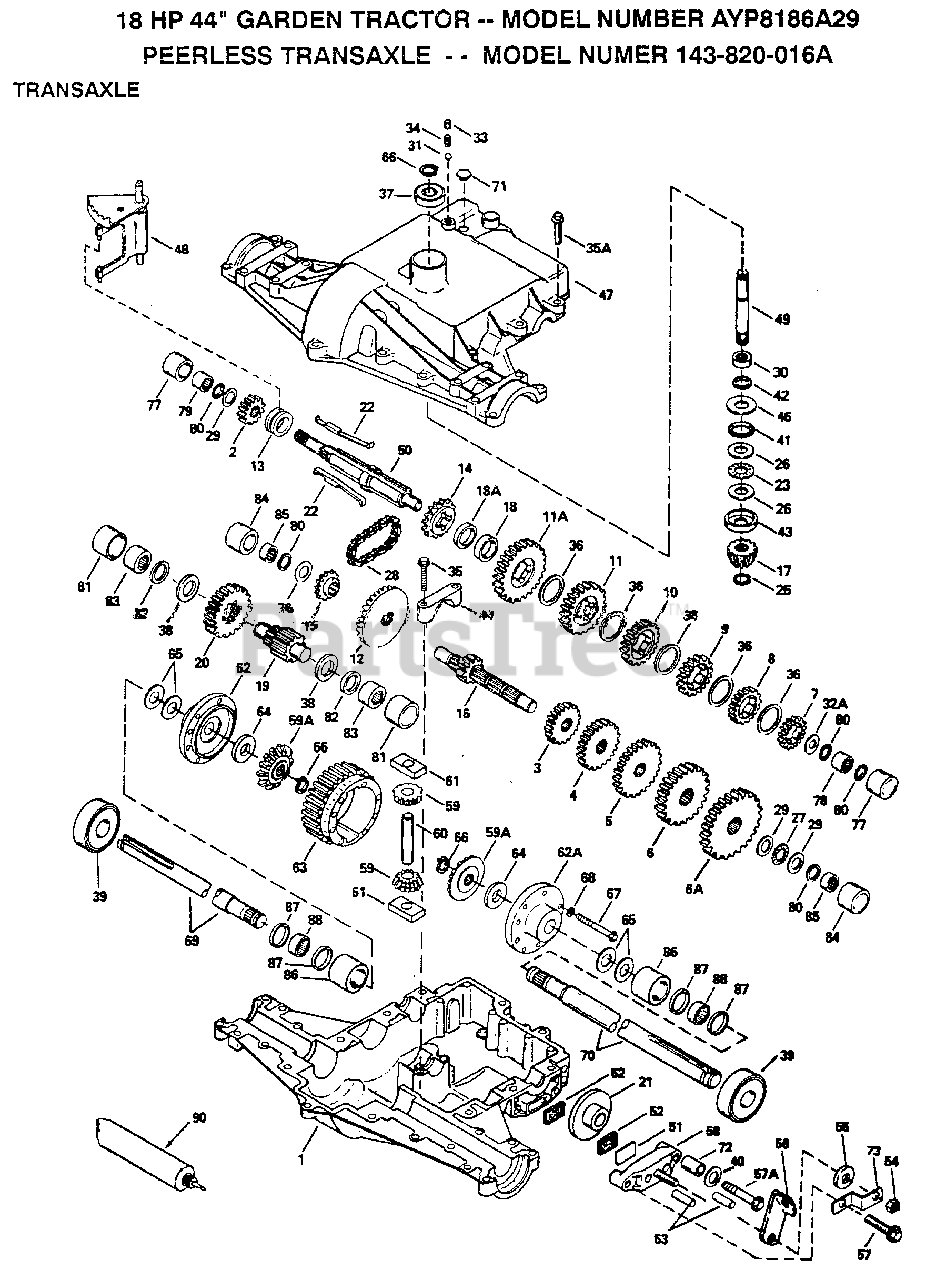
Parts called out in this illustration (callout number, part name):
1	CASE TRANSAXLE
2	GEAR, SPUR, 15T
3	GEAR, SPUR, 12 TEETH
4	GEAR, SPUR, 18 TEETH
5	GEAR, SPUR, 25T
6	GEAR, SPUR, 28T
6A	GEAR, SPUR, 31T
7	GEAR, SPUR, 19T
8	GEAR, SPUR, 22T
9	GEAR, SPUR, 25T
10	GEAR, SPUR, 32 TEETH
11	GEAR, SPUR, 37 TEETH
11A	GEAR, SPUR, 41T
12	GEAR BEVEL, 33T
13	COLLAR SHIFT
14	SPROCKET 18T (REV)
15	SPROCKET 9T
16	SHAFT COUNTER
17	BEVEL PINION, 13T
18	SPACER, .350/.340 THICK
18A	SPACER, .276/.268 THICK
19	SHAFT, OUTPUT, 9T
20	GEAR, OUTPUT, 35T
23	BEARING THRUST
25	RETAINING RING
26	WASHER THRUST
27	THRUST BEARING
28	CHAIN, ROLLER
29	WASHER THRUST
30	BEARING NEEDLE
31	BALL STEEL, 5/16" DIA.
33	SCREW, 3/8-16 X 3/8"
35	SCREW, 1/4-20 X 1-1/4
35A	SCREW HEX HD 5/16-18 X 1-1/4
36	WASHER THRUST
37	BEARING BALL
38	WASHER THRUST
39	BEARING BALL
40	WASHER FLAT
42	OIL SEAL 3/4
43	WASHER CUPPED
44	BEARING CAP
47	COVER TRANSAXLE
48	ROD AND FORK ASSY SHIFT
49	SHAFT INPUT
50	SHAFT BRAKE
51	PLATE BRAKE PAD
54	LOCKNUT 5/16-24
55	WASHER, FLAT
56	LEVER BRAKE
57	SCREW, 1/4-20 X 1-1/4
57A	SCREW FLNG HEX 1/4-20 X 2-1/4
58	HOLDER BRAKE PAD
59	PINION, 10T
61	BLOCK DRIVE
62	CARRIER DIFF THREADED HOLES
62A	CARRIER DIFF
63	GEAR, RING, 31T
65	WASHER THRUST
67	SCREW, 1/4-20 X 2-1/4
68	WASHER LOCK 1/4
69	AXLE, 12-5/16" LONG
70	AXLE, 16-3/16" LONG
71	PLUG, THRDED, 9/16-18
73	BRKT BRAKE LEVER
78	BEARING NEEDLE
79	BEARING NEEDLE
81	SLEEVE STEPPED
82	RING SQ CUT
83	BEARING NEEDLE CAPPED
84	SLEEVE STEPPED
85	BEARING NEEDLE CAPPED
86	SLEEVE STEPPED
87	RING SQ CUT
88	BEARING NEEDLE
90	GREASE BENTONITE, 32 OZ.
